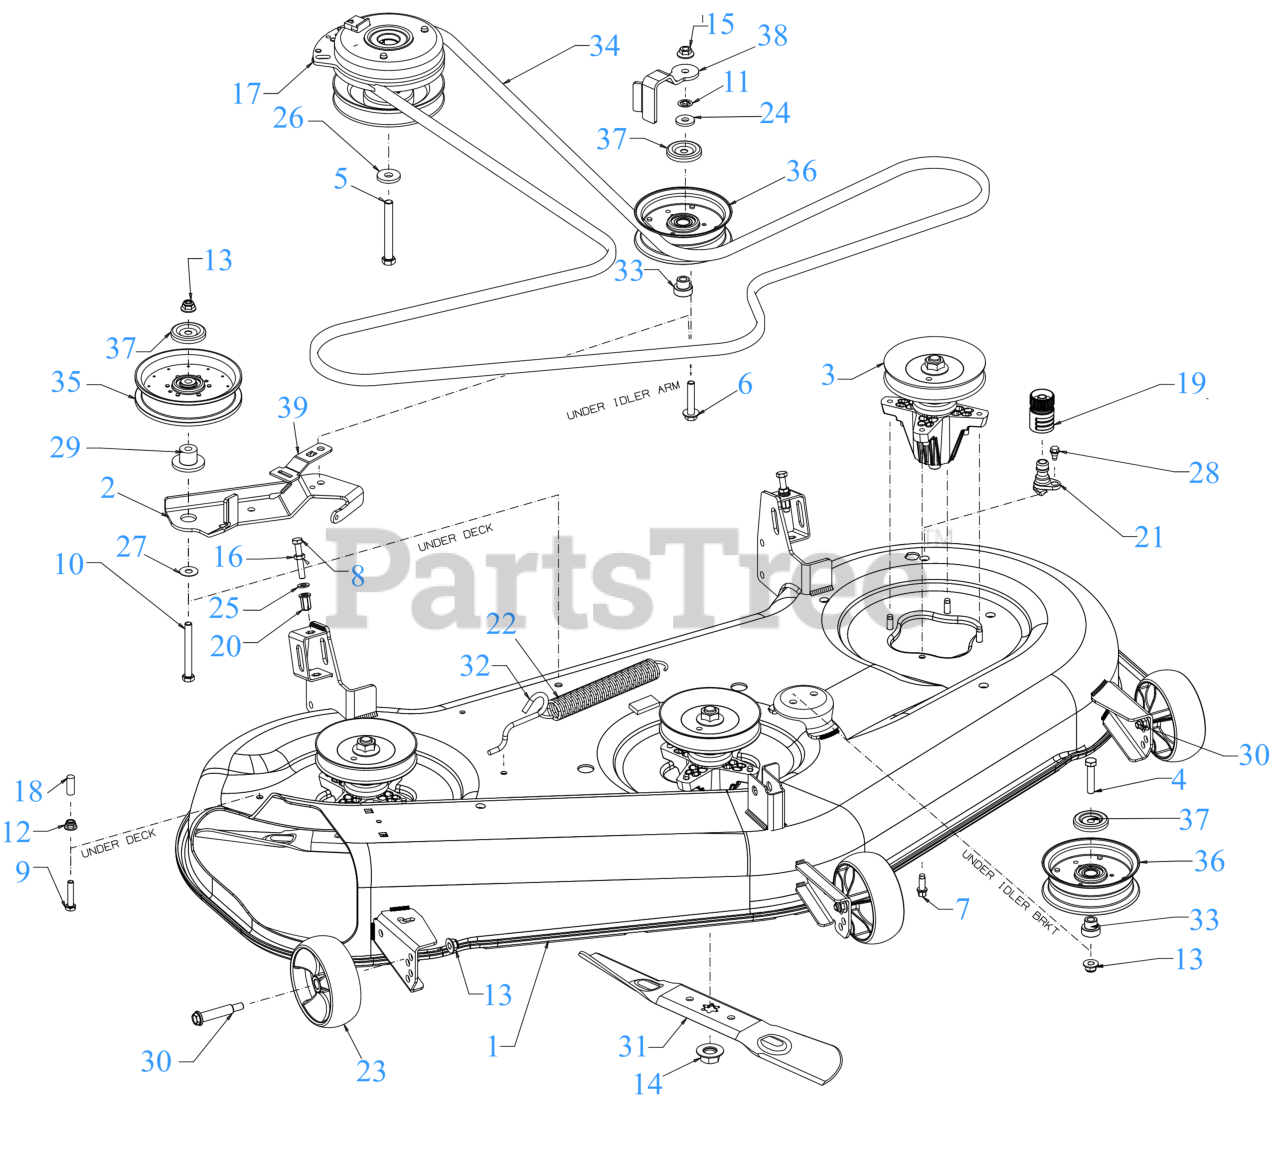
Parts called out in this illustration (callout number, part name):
1	54" DECK SHELL
2	DECK IDLER BRACKET
3	SPINDLE ASSEMBLY
3	Cub Cadet 54" SPINDLE (06978 W/HDW)
4	HEX SCREW 3/8-16 x 1.75 GR5
5	SCREW 7/16-20 x 3.5 GR5
6	SCREW 3/8-16 x 2.0
7	SCREW 5/16-18 x .875
8	SCREW-FULL THREAD 5/16-18 GR5
9	SCREW 5/16-18 x 1.5 LG
10	SCREW 3/8-16 x 3.25 GR8
11	PUSH NUT
12	FLANGE LOCK NUT 5/16-18
14	HEX NUT
15	FLANGE LOCK NUT
16	HEX NUT
17	ELECTRIC PTO CLUTCH
18	VINYL CAP
19	WATER NOZZLE ADAPTER
20	NUT RIVET 5/16-18
21	DECK WASH NOZZLE
22	EXTENSION SPRING
23	DECK WHEEL (5.0 DIA x 1.875)
24	FLAT WASHER .385 x 1.00 x .135
25	FLAT WASHER
26	FLAT WASHER .445 x 1.248 x .170
27	FLAT WASHER
28	SHOULDER SCREW 1/4-20 x .50
29	SHOULDER SPACER
30	SHOULDER BOLT (.50 X 2.0 x 3/8 -16)
31	18.61" BLADE (2N1)
31	Cub Cadet 54" HI LIFT BLADE SET
31	Genuine Factory Parts 54" BLADE SET
31	54" 6 PT STAR LOW LIFT/SAND BLADE
31	Cub Cadet 54" LOWLIFT BLADE SET
31	Genuine Factory Parts 54" LOWLIFT BLADE SET
31	54" 6 PT STAR XTREME MULCH BLADE
31	Cub Cadet 54" XTREME BLADE SET
31	Genuine Factory Parts 54" XTREME MULCH BLADE SET
32	DECK SPRING HOOK
33	SHOULDER SPACER
34	V-BELT B SEC x 148.25
34	Cub Cadet 54" DECK DRIVE BELT
34	Troy-Bilt 54" DECK DRIVE BELT
35	FLAT IDLER PULLEY
36	IDLER PULLEY 4.50" DIA
37	IDLER PULLEY CAP
38	BELT KEEPER
